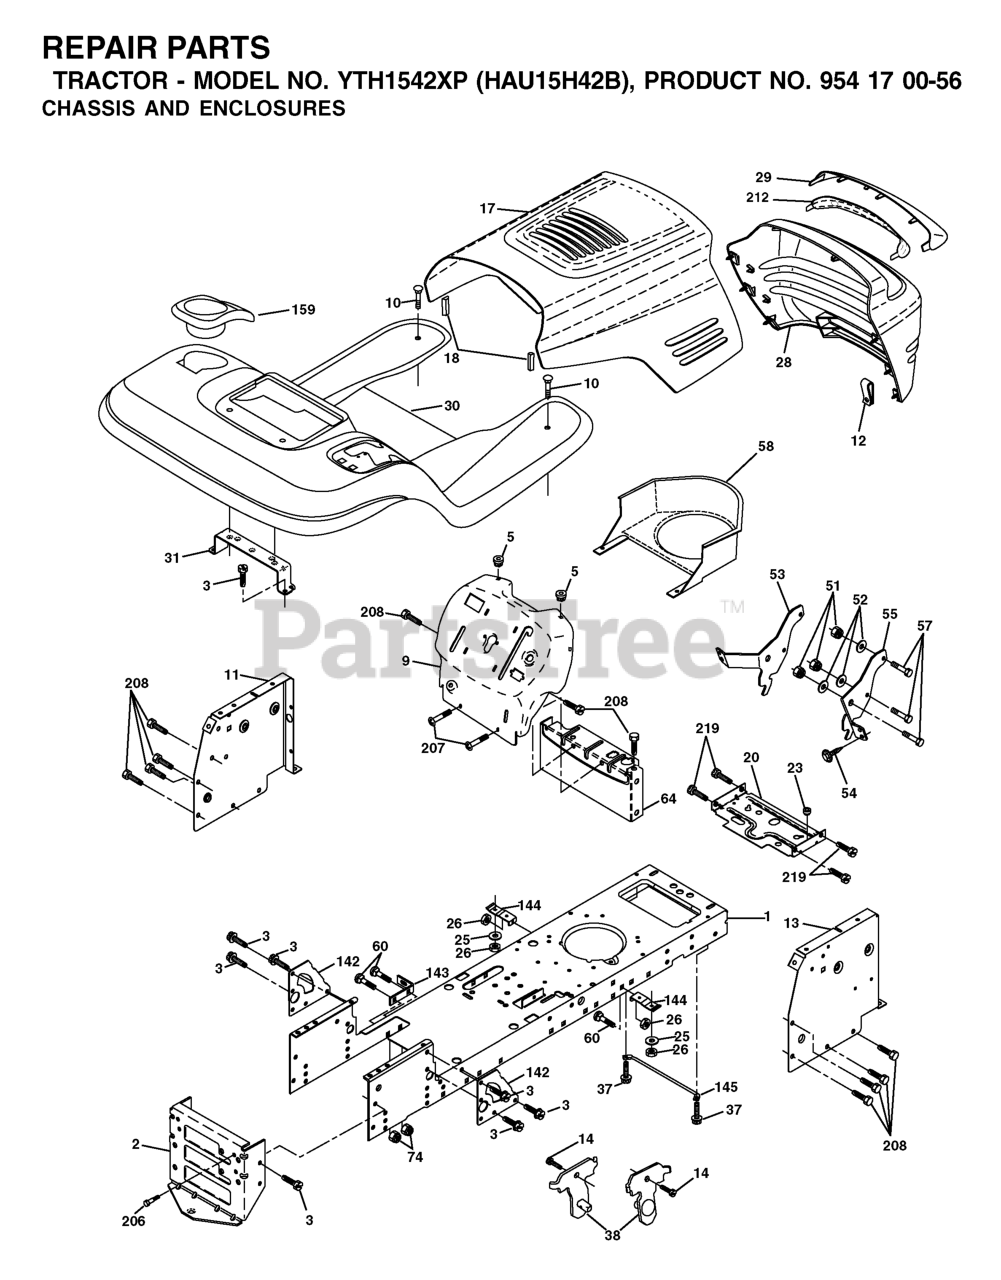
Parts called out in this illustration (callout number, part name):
1	CHASSIS STAMPING
2	DRAWBAR, 12GA
3	SCREW 3/8-16X3/4
5	BUMPER.RUBBER.HOOD
9	DASH SLKSCR
10	BOLT D
11	PANEL.DASH.LH.LTX
13	PANEL ASM, DASH RH
14	SCREW LT
17	HOOD ASM.
18	BUMPER HOOD T
20	PLATE MTG.BATTERY/FUEL TANK
23	BUSHING.SNAP.NYL.BLK.
25	WASHER
26	NUT
28	GRILLE/LENS ASM
29	LENS
30	FENDING
31	BRACKET.SUPPORT.FENDER
37	Screw 5/16-18 x 1/2 Hex, Self Tapping 5/16-18 x 1/2
38	BRACKET.ASM.PIVOT.MOWER.REAR
51	LOCKNUT.NYLOC.1/4-20
52	WASHER
53	BRACKET.GRILLE.LH
54	SCREW.HEX.WS.HD.8-18 X 7/8
57	BOLT
58	DUCT, INTAKE AIR
60	Bolt - Rd. Hd. Sq. Neckiage 3/8 16 x 3/4
64	DASH LOWER
142	PLATE REINFORCEMENT
143	BRACKET, SWAY BAR
144	BRKT, FOOT REST
145	ROD PIVOT CHASSIS/HOOD
159	CUPHOLDER
206	SHOULDER BOLT 5/16-18TT
207	SCREW, 5/16-18 X 1/2
208	SCREW 3/8-16X1/2
212	REPL BY 532 1745-03
